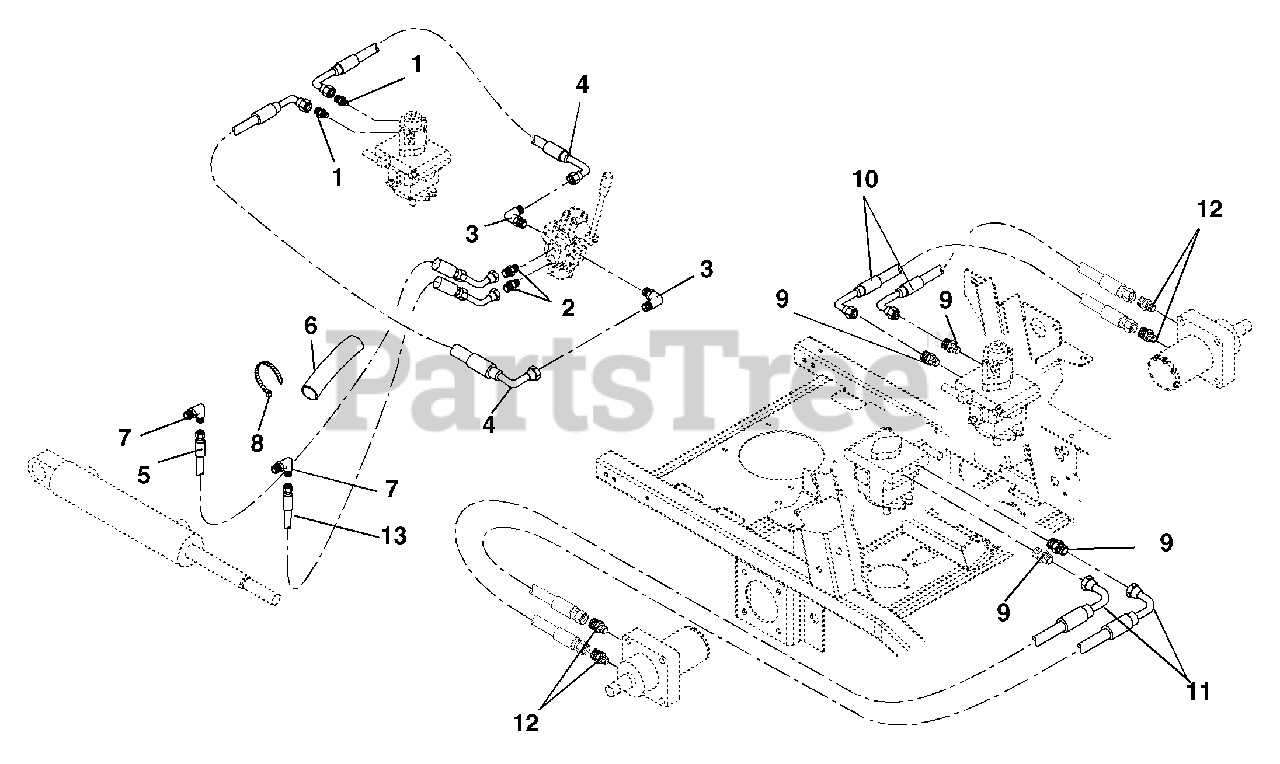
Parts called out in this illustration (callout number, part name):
1	FITTING, HYD (4 F5OLO)
2	FITTING, HYD (4-6 F5OLO)
3	FTG, HYD ELBOW M4F-M8O
4	HOSE,HYD .25-17-2K F04F9-F04F9
5	HOSE,HYD .25-47-2K F04F0-F04F4
6	SLEEVE, PROTECTIVE
7	FITTING, HYD (4 C5OLO)
8	CABLE TIE LG 5-1/2
9	ADPTR,FACE SEAL 8X8 1/2 O-RING
10	HOSE,HYD .50-19-2K F08F9-F08F9
11	HOSE,HYD .50-20-2K F08F0-F08F0
12	FTG, HYD STR M10O-M8F
13	HOSE,HYD.25-42-2K F04F0-F04F4
